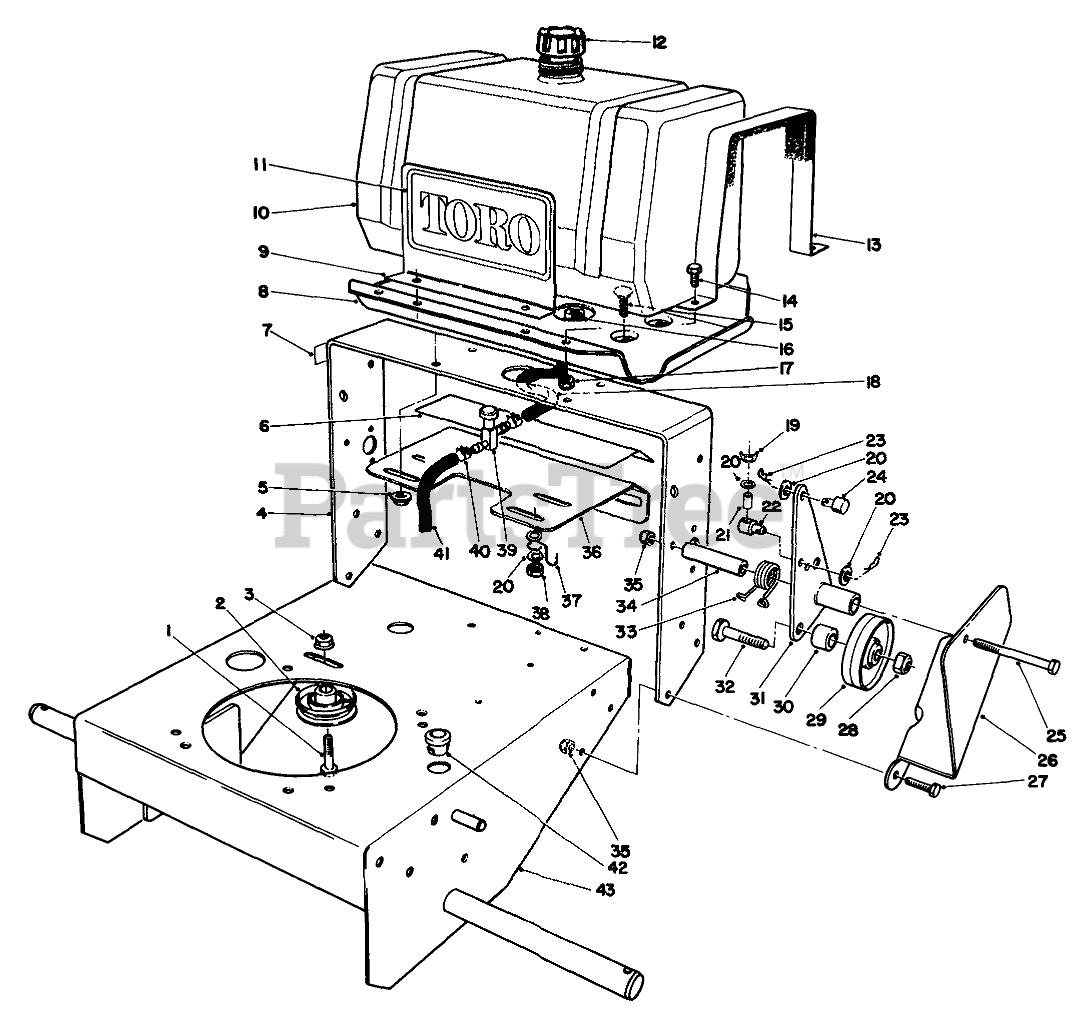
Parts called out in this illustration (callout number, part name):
1	SCREW-HH
2	PULLEY-IDLER
3	NUT-HF
4	Frame-Rear
5	NUT-HF
6	Decal-Ground Speed
7	Decal-Fuel Shut Off
8	PLATE-FUEL TANK
9	DECAL-PLATE
10	TANK-FUEL
11	DECAL
12	GAS CAP ASM
13	STRAP ASM
14	SCREW-HH
15	SCREW-CARR
16	CLAMP-HOSE
17	NUT-LOCK, NI
18	GAS HOSE
19	NUT-WING
20	WASHER-PLAIN
21	BUSHING-NYLON
22	FITTING-ROD
23	PIN-COTTER
24	ROD FITTING
25	SCREW-HH
26	Bracket-LH
27	SCREW-HH
28	NUT-LOCK, NI
29	IdlerWheel
30	WHEEL IDLER SPACER
31	Bracket-Idler, LH
32	SCREW-LEVELER
33	SPRING-TORSION, LH
34	PIVOT-IDLER SPACER
35	NUT-LOCK, NI
36	Plate
37	GAS LINE CLIP
38	NUT-LOCK, NI
39	FUEL VALVE
40	CLAMP-HOSE
41	GAS HOSE
42	GROMMET
43	Frame
